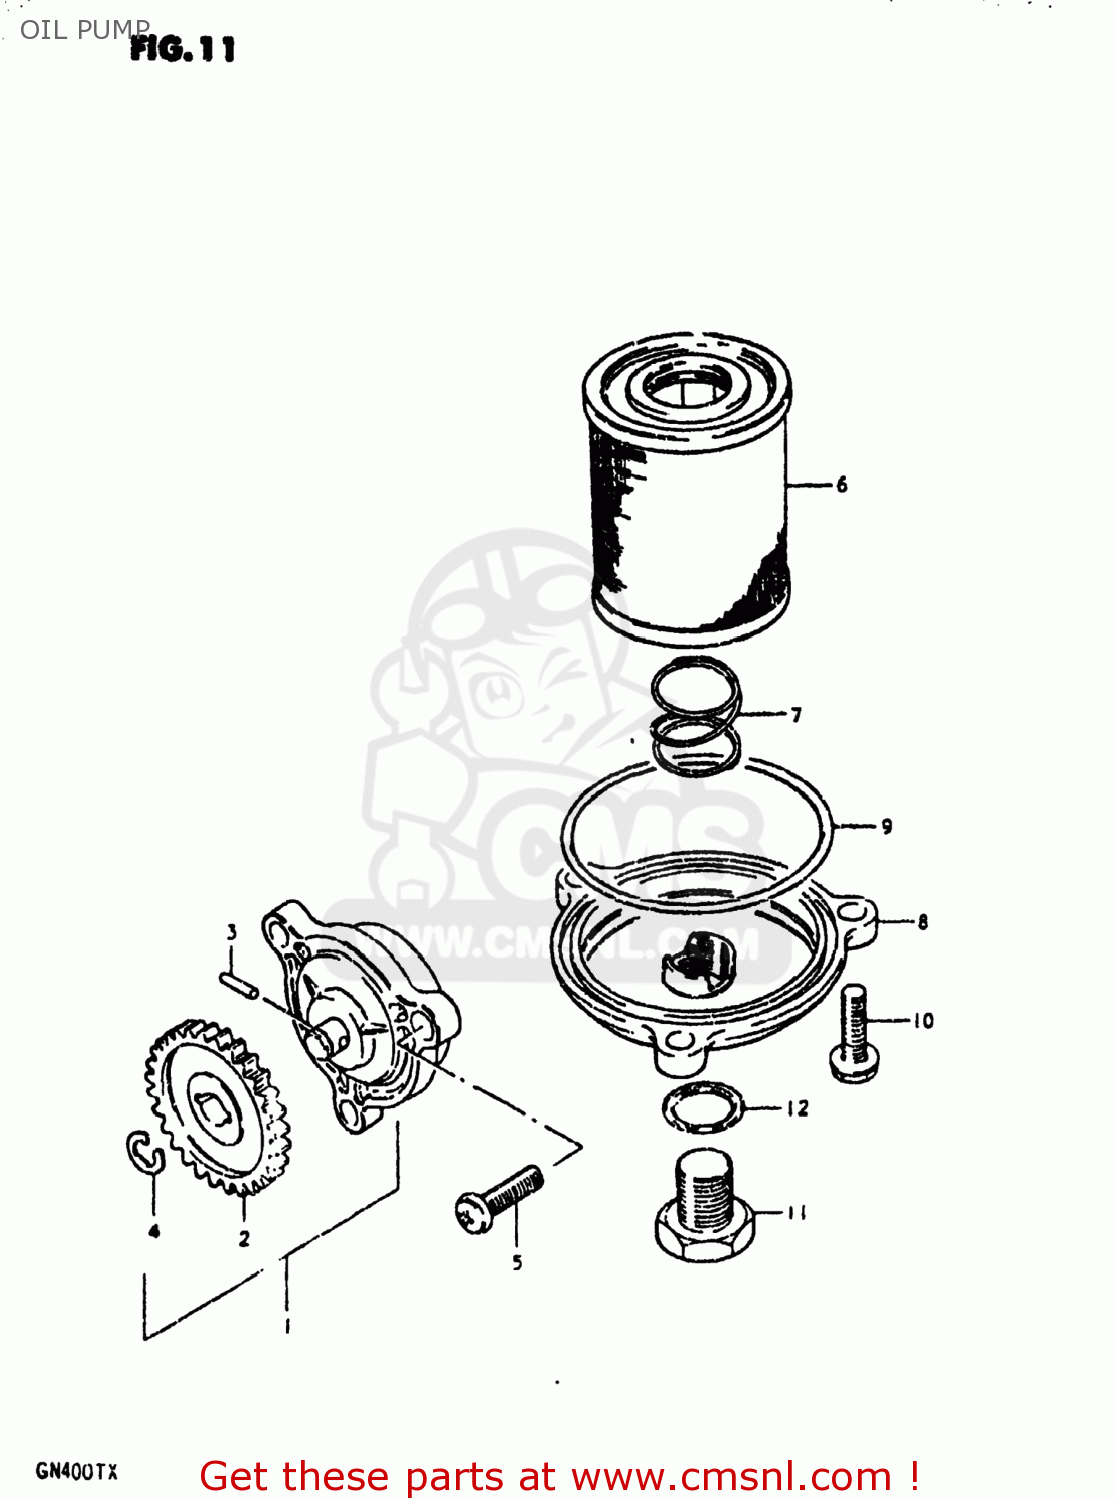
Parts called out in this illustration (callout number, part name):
1	PUMP ASSEMBLY,ENGINE OIL
2	GEAR,OIL PUMP DRIVEN
3	PIN(2.5X11.8)
4	E RING 6MM
5	SCREW
6	STRAINER,OIL
7	SPRING
8	CAP,ENGINE OIL STRAINER
9	O RING(D:2.4,ID:62.6)
10	BOLT,REAR
11	PLUG
12	GASKET(14X19.2X2) (NAS)
